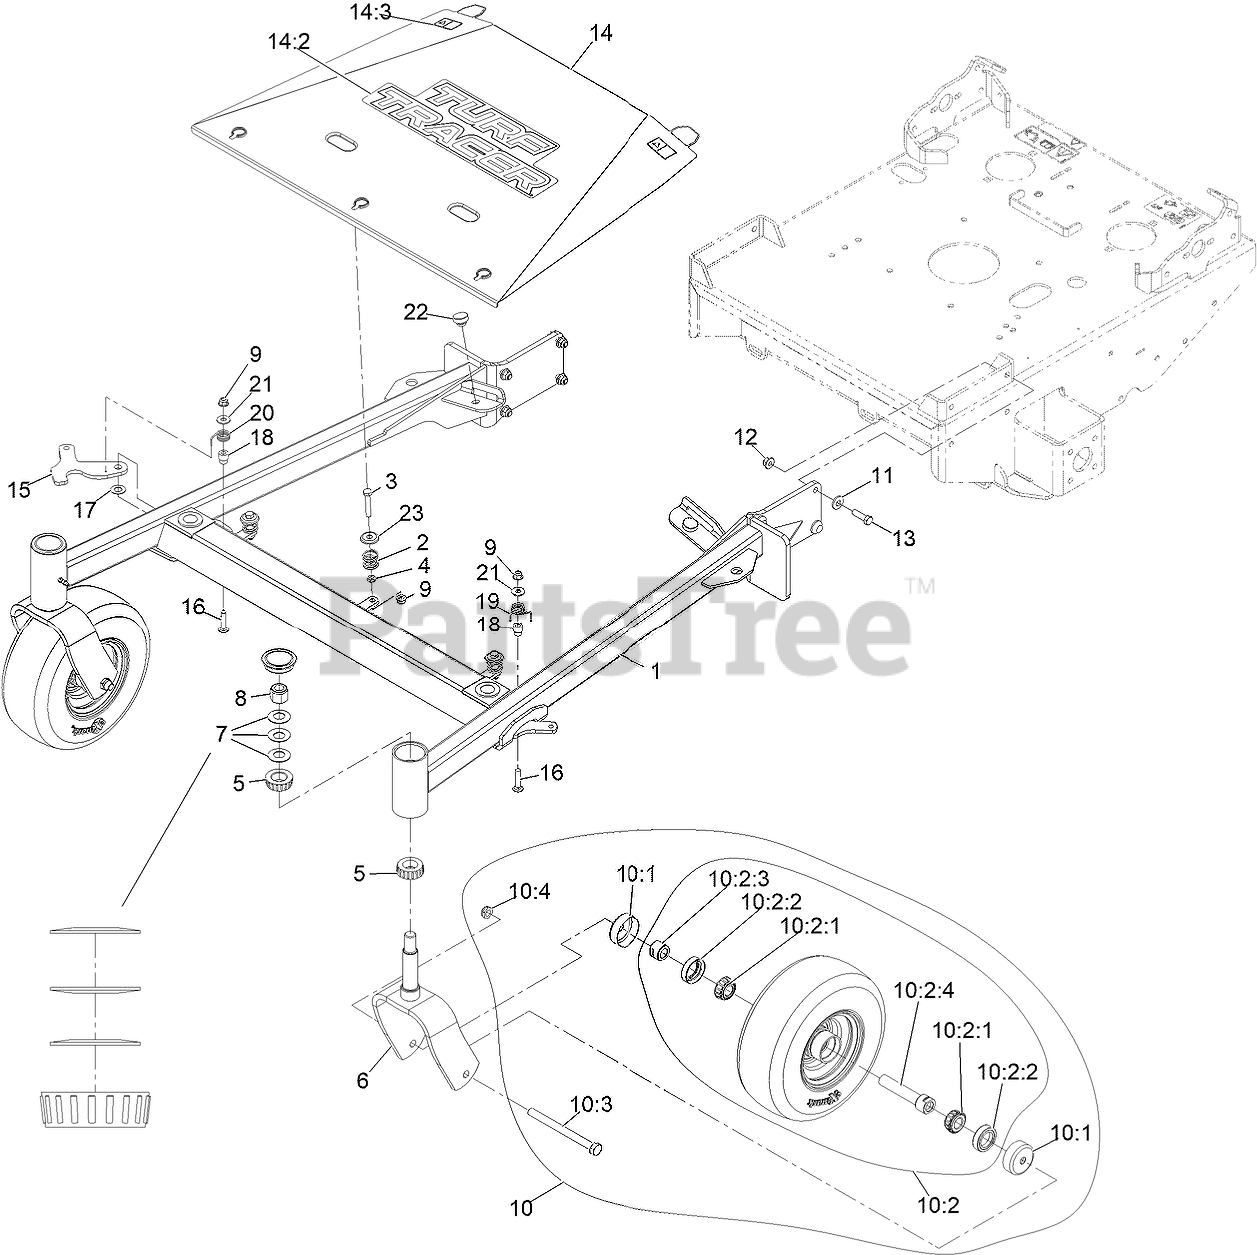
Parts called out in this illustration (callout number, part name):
1	ASM-52" Ttx Front Frame
3	SCREW-HH
4	NUT-JAM
5	Cone-Bearing Tapered Roller
6	WLD, CASTER FORK
7	WASHER-BELLVILLE
8	NUT-LOCK, NI
9	NUT-HF, NI
10	ASM,WHEEL&BEARINGS
10:1	GUARD-SEAL
10:2	Wheel And Bearing ASM
10:2:1	BEARING-CONE, TAPERED ROLLER
10:2:2	SEAL-CASTER
10:2:3	SPACER-NUT
10:2:4	CASTER AXLE ASM
10:3	SCREW-HH
10:4	NUT-HEX
11	WASHER-BELLEVILLE
12	NUT-HF, NI
13	SCREW-HH
14	ASM-52" Ttx Center Shield
14:2	DECAL-TURF TRACER
14:3	DECAL-WARNING
15	LATCH, DECK HEIGHT
16	BOLT-CARR
17	Washer-Plastic
18	COLLAR-BASKET
19	SPRING-TORSION, LH (YELLOW)
20	Spring-Torsion, RH
21	WASHER-FLAT
22	BUMPER-RUBBER
23	Washer-Cup
